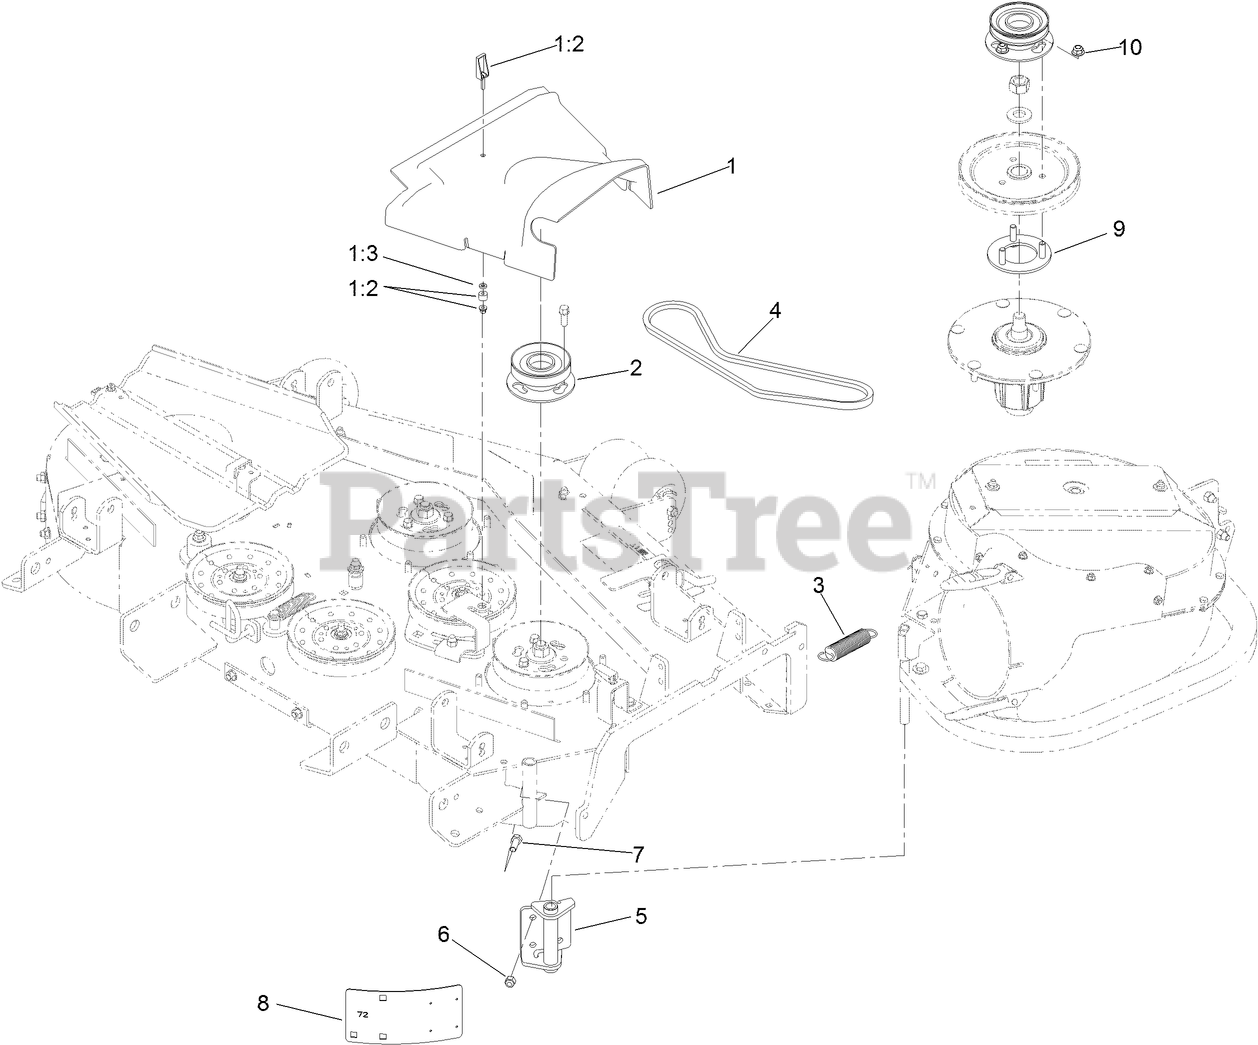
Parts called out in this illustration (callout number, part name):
1	BELT COVER ASM
1:2	LATCH-SWELL
1:3	WASHER
2	PULLEY-BLOWER
3	SPRING-EXTENSION
4	BELT-V
6	NUT-LOCK, NI
7	SCREW-HH
8	TEMPLATE
9	PULLEY MOUNT ASM
10	NUT-HF, NI
